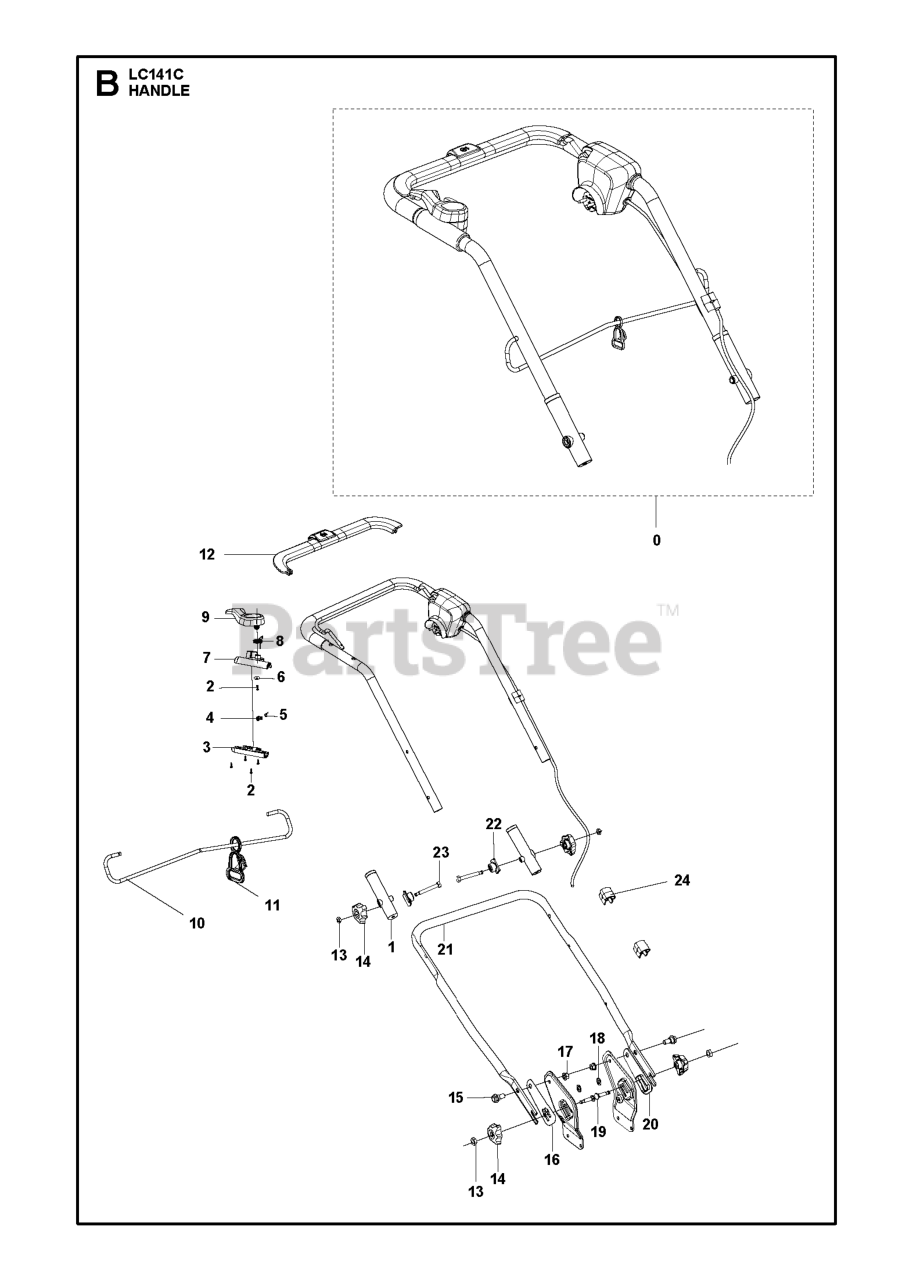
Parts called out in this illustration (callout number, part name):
8	TORSION SPRING
9	COVER BAIL STOP SOLUTION
13	HEXAGON NUT #26800502301
14	KNOB #25341500101
16	PLATE RIGHT
17	LOCKING BOLT M8,GB6187.1 #2680
18	SPACER RING
20	PLATE LEFT
24	HOLDER CABLE
